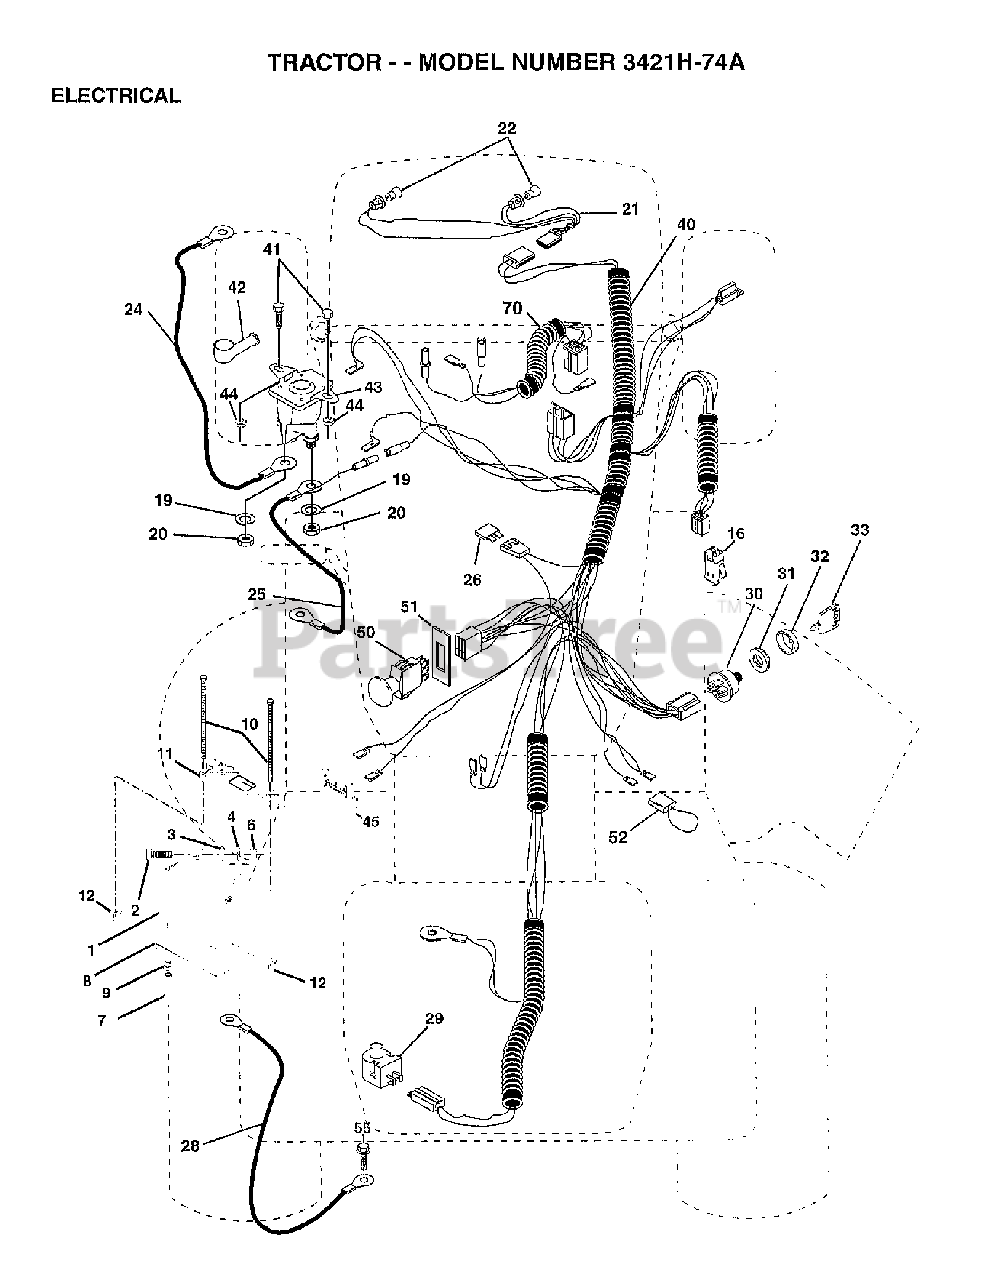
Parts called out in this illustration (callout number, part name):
2	BOLT.HEX.1/4.X.3/4.DICHROMATE
3	WASHER
4	LOCKWASHER
6	NUT
7	BATT DRAIN TUBE T
8	TRAY.BATTERY
9	HOSE CLAMP T
10	BOLT 1/4-20 X 7.5
11	BATTERY HOLDDOWN
20	NUT
22	LIGHTBULB
24	CABLE BATTERY 6 GA 22" W/16W
25	BATTERY CABLE
26	FUSE *
28	CABLE GROUND 6 GA 21" 90T BLK
29	SWITCH SEAT
30	SWITCH.IGNITION.4.POSITION
31	NUT
32	COVER KEY IGNITIO
33	KEY.MOLDED.GENERIC
41	BOLT
42	TERMINAL COVER
43	Solenoid Kit, .95
44	NUT.HEX.KEPS.1/4-20
51	RETAINING RING
52	WIRE PROTECTION LOOP
55	SCREW LT
